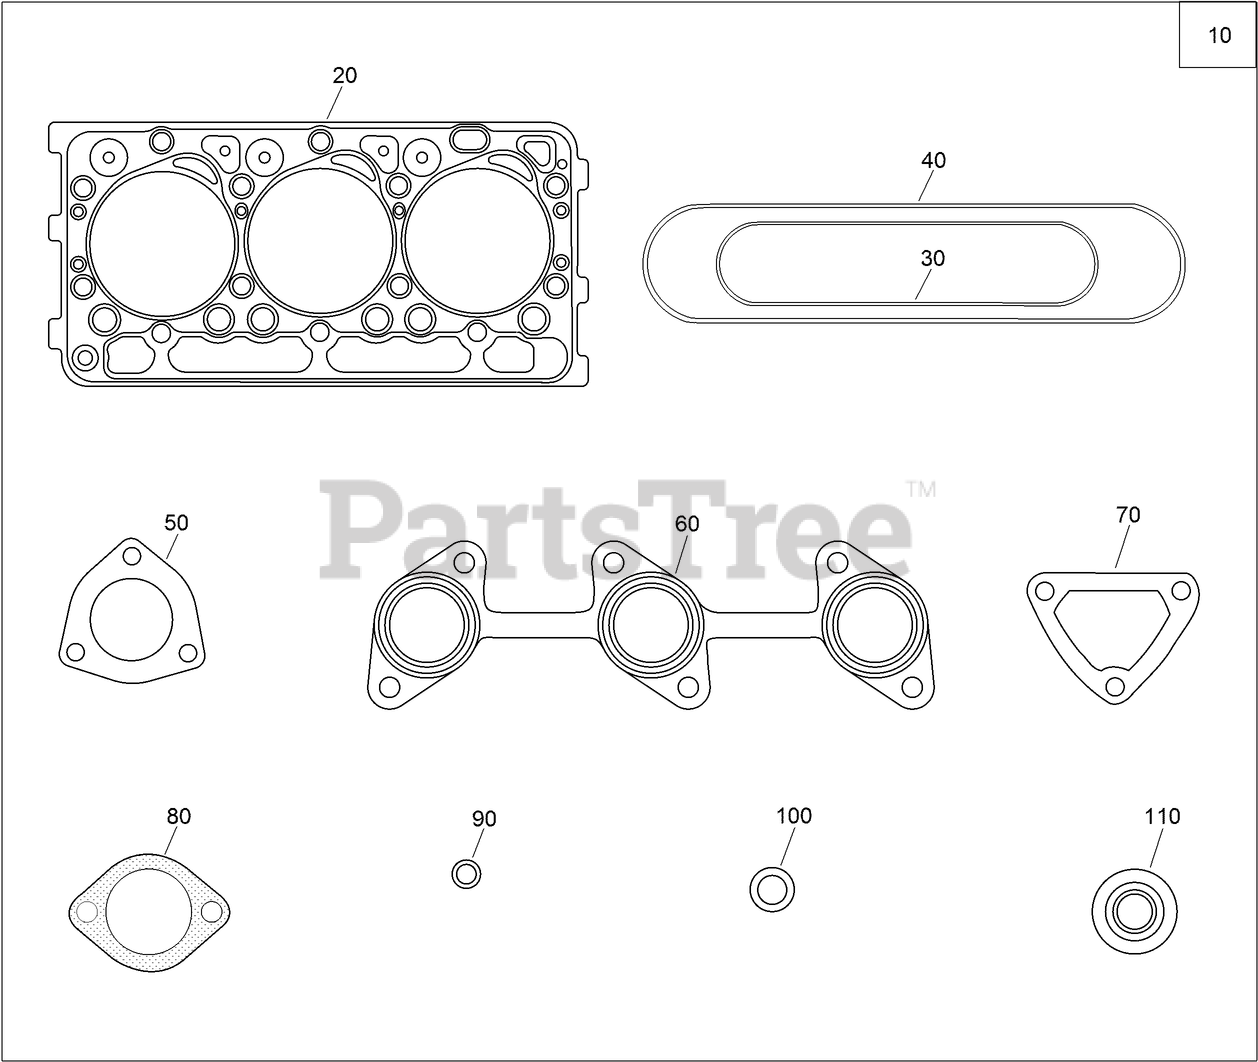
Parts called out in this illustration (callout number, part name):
10	UPPER GASKET KIT
20	GASKET-HEAD, CYLINDER
30	GASKET-COVER, HEAD
40	GASKET-MANIFOLD, INTAKE
50	GASKET-MUFFLER
60	GASKET-MANIFOLD, EXHAUST
70	GASKET-FLANGE, WATER
80	GASKET-THERMOSTAT
90	O-RING
100	GASKET
110	SEAL-STEM, VALVE
